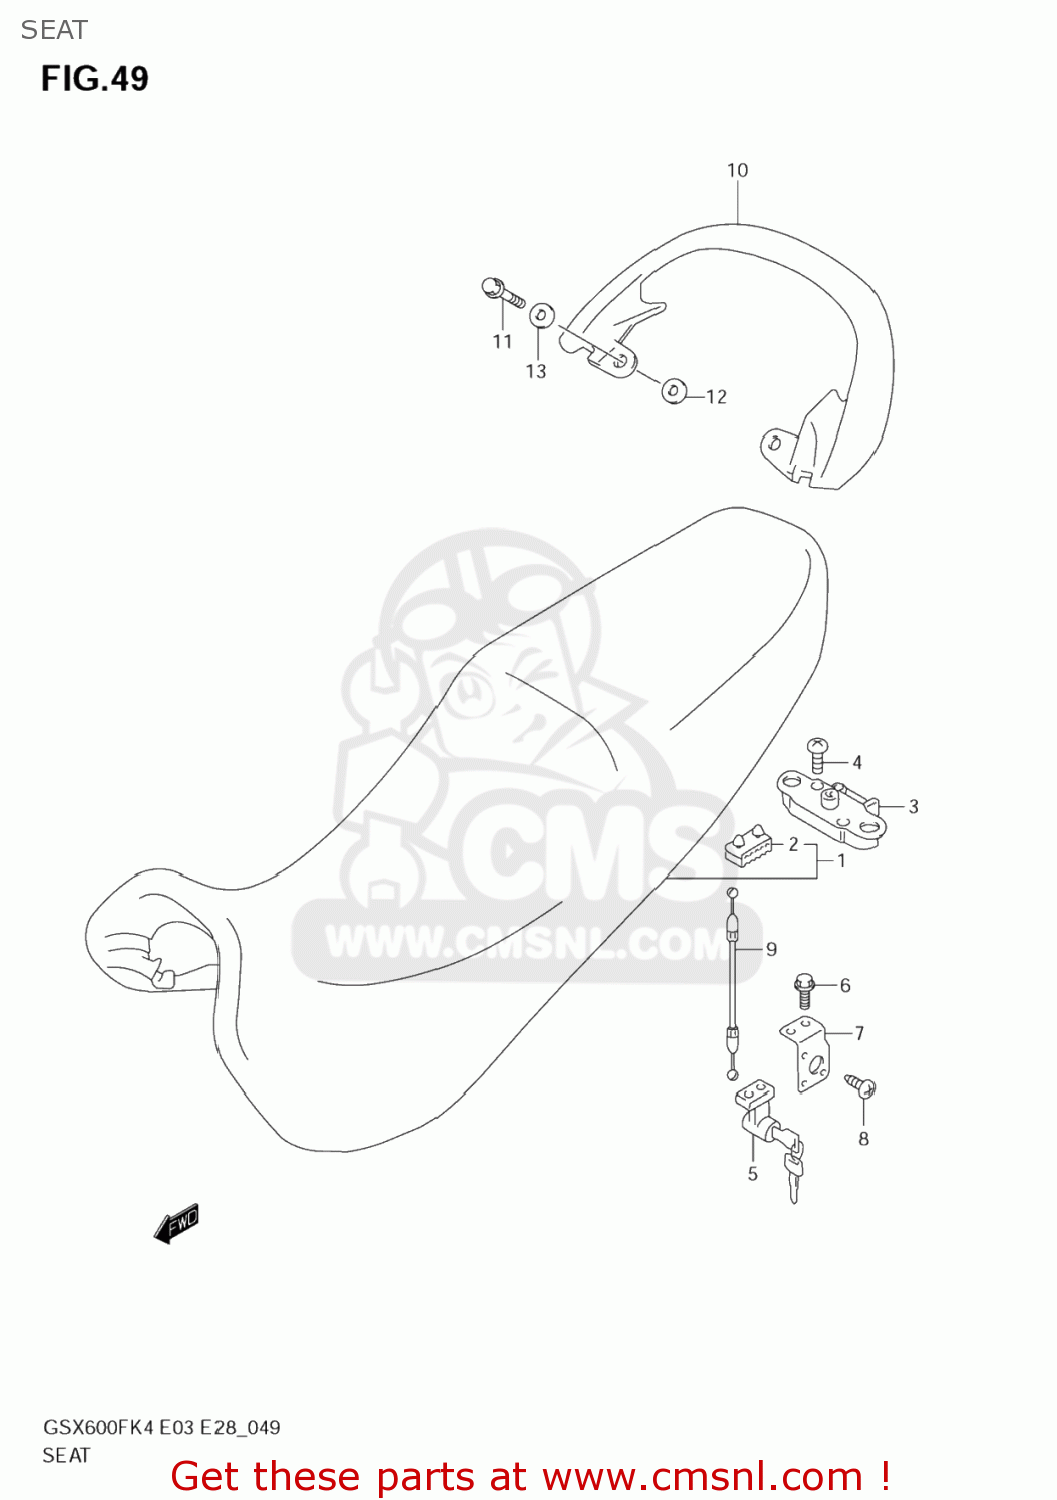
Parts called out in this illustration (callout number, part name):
1	SEAT ASSY
2	CUSHION
3	BRACKET,SEAT SUPPORT,RIGHT
4	SCREW
5	LOCK SET,SEAT
6	BOLT
7	BRACKET,SEAT LOCK
8	SCREW
9	CABLE,SEAT LOCK
10	HANDLE,PILLION RIDER
11	BOLT.MUF SPRT F
12	CUSHION,RIDER HNDL(17X24X1.5)
13	WASHER(8.5X24X2.3)
